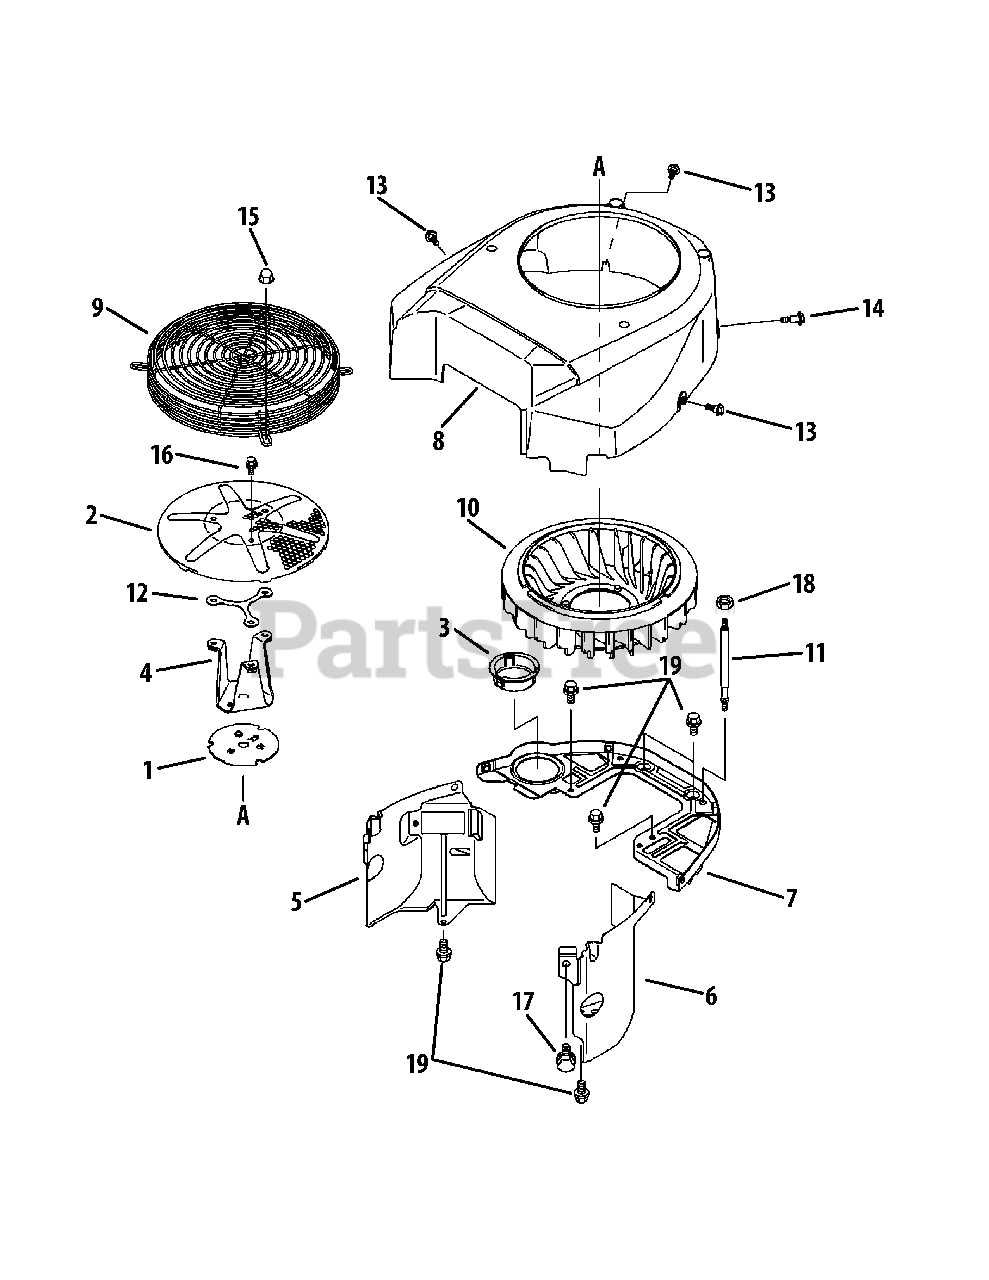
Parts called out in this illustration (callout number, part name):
4	Grass Screen Bracket
5	Engine Shroud
6	Engine Shroud
7	Engine Shroud
11	Stud
14	Bolt
18	Hex Nut
19	Bolt, 6 x 12
